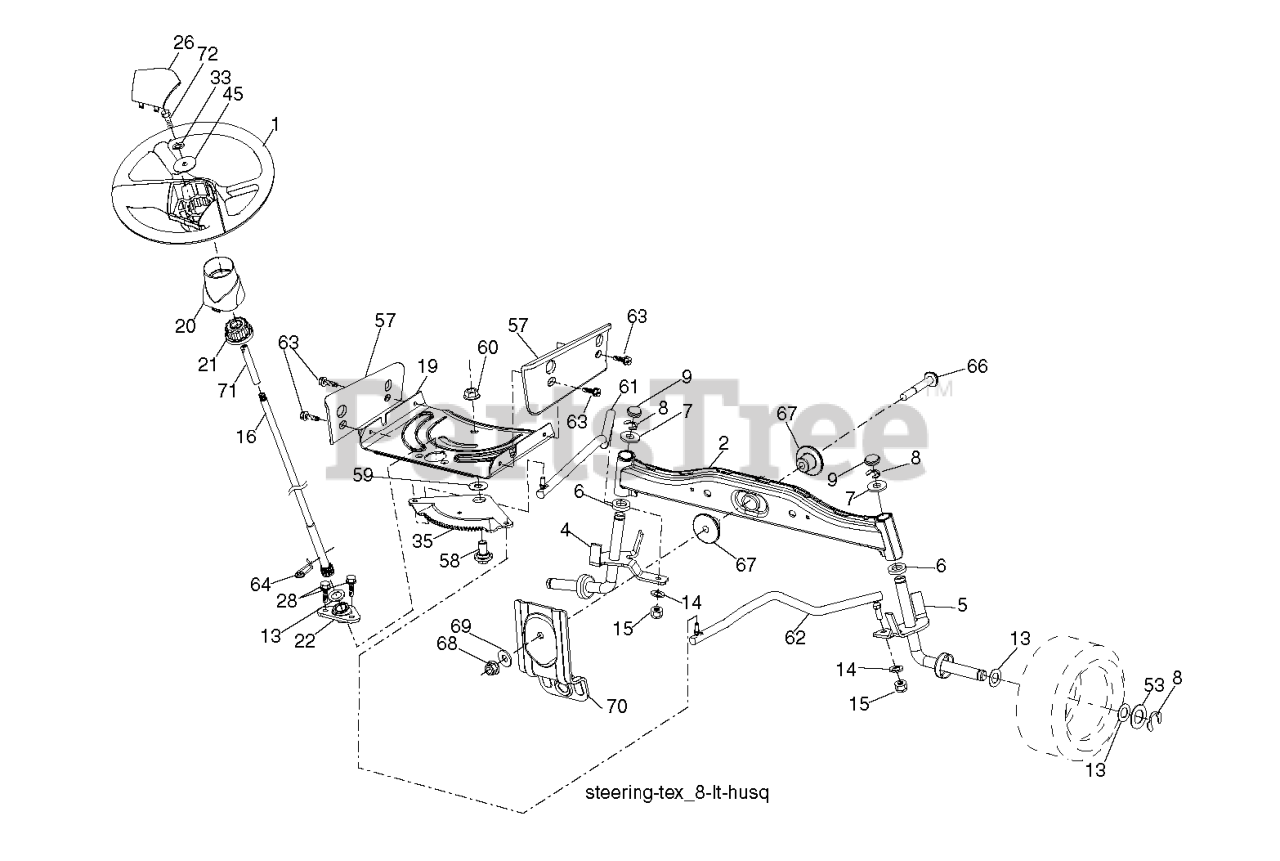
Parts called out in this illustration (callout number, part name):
1	STEERING WHEEL
2	AXLE.CAST.IRON
4	SPINDLE.WELDED.LH.15"TEX
5	SPINDLE.WELDED.RH.15"T
6	THRUST WASHER
9	CAP.SPINDLE.BLACK
14	WASHER, LOCK 3/8
15	NUT CROWNLOCK 3/8-24
16	SHAFT STEERING
19	PLATE.STEER.DDL.NLT/NG
20	BOOT, STEERING
21	ADAPTER, WHEEL STNG..
22	BUSHING.ASM.STEERING.A
26	INSERT.CAP.STRG.WH.GRAY
28	SCREW, 3/8-16X3/4
33	WASHER.LOCK.HVY.HLCL.SPR.5/16
35	GEAR.SECTOR.PLATE.DDL.
45	WASHER.11/32
53	WASHER.HARDENED
57	BRACKET.UPSTOP.TEX
58	BOLT.SHOULDER.SECTOR.P
59	WASHER.THURST.SECTOR.S
60	NUT FLANGE LOCK 5/8-11
61	DRAGLINK.LH.BALLSTUD.D
62	DRAGLINK.RH.BALLSTUD.D
63	SCREW
64	RETAINER.CLIP.SPRING.S
66	BOLT HEX FGHD 7/16-14 X 3 SERR
67	BUSHING.PM.FRONT AXLE
68	NUT.LOCK.FLANGE.7/16
69	WASHER.1.5X.505X.118
70	BRKT.DECK.SUSPENSION.F
71	SHAFT EXTENSION STEERING
72	BOLT YT
